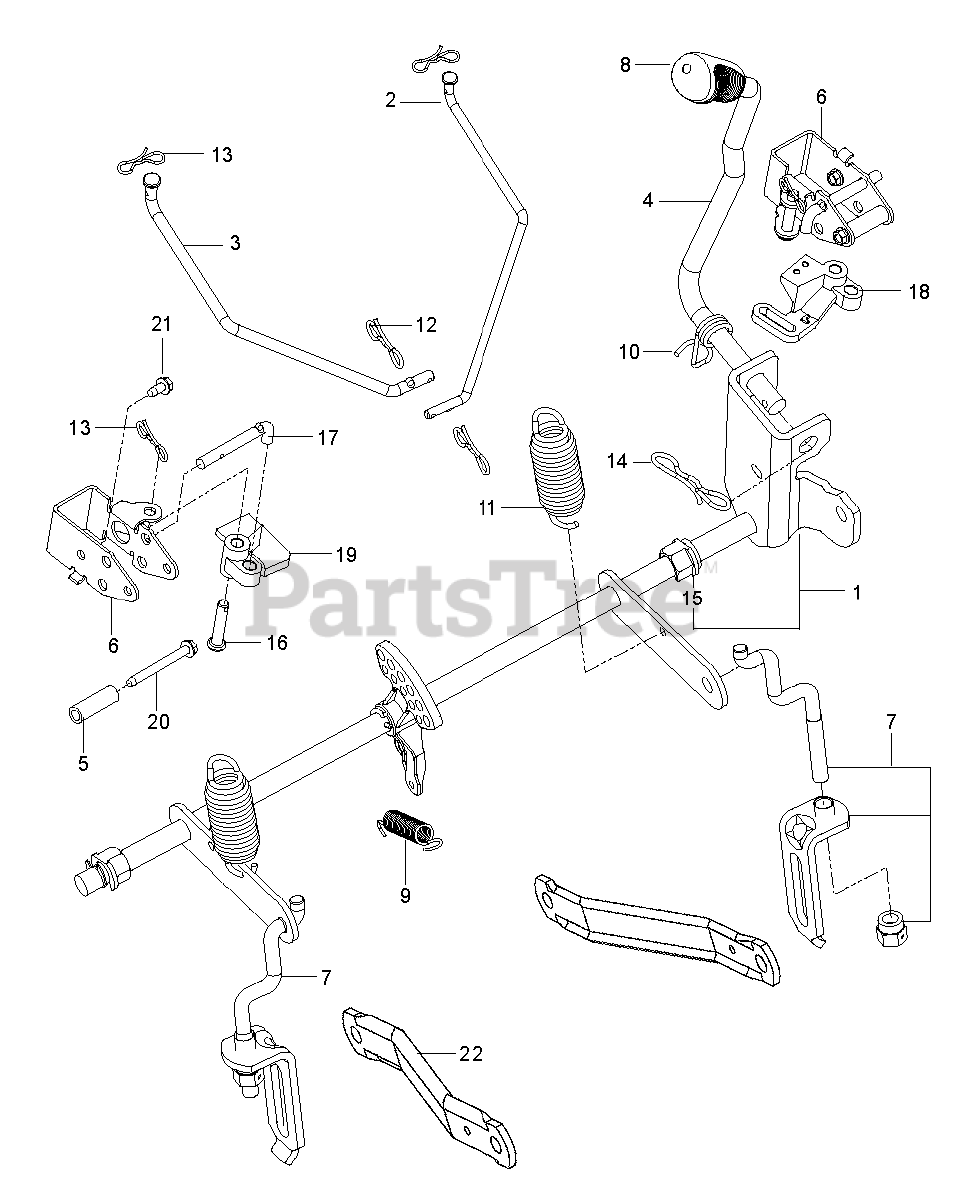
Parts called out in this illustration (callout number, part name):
1	SHAFT.ASM.RZ.DECK.LIFT.SRV
2	LINK.BRAKE.PARK.UPPER.LH
3	LINK.BRAKE.PARK.UPPER.RH
4	LIFT.LEVER.ASM.RZ.SERVICE
5	SPACER.334.ID.5.OD.1.5.L
6	BRACKET.BELLCRANK.PBRAKE X431
7	LINK.ASM.RZ.LIFT.SERVICE
8	GRIP.HANDLE.LIFT.PVC.428
9	RETURN.BRAKE.PARK.AUTO
10	SPRING.TORSION.LIFT.HANDLE
11	SPRING
12	PIN.COTTER.5/16.BOW TI
12	PIN COTTER;LOCKING;BOWTIE;1IN
13	PIN COTTER;LOCKING;BOWTIE;1IN
13	PIN.COTTER.7/16.BOW TI.
14	PIN.COTTER.5/16.BOW TI
14	PIN.COTTER.7/16.BOW TI.
15	PLASTIC NUT
16	PIN.5.16X1.5
17	BELLCRANK.RH
17	ROD.PUSH.BRAKE
18	BELLCRANK.LH
19	BELLCRANK.RH
20	SCREW THD;ROLL;1/4-20 X 2.25
21	SCREW.1/4-20X5/8
22	ARM.SUSPENSION.MOWER
